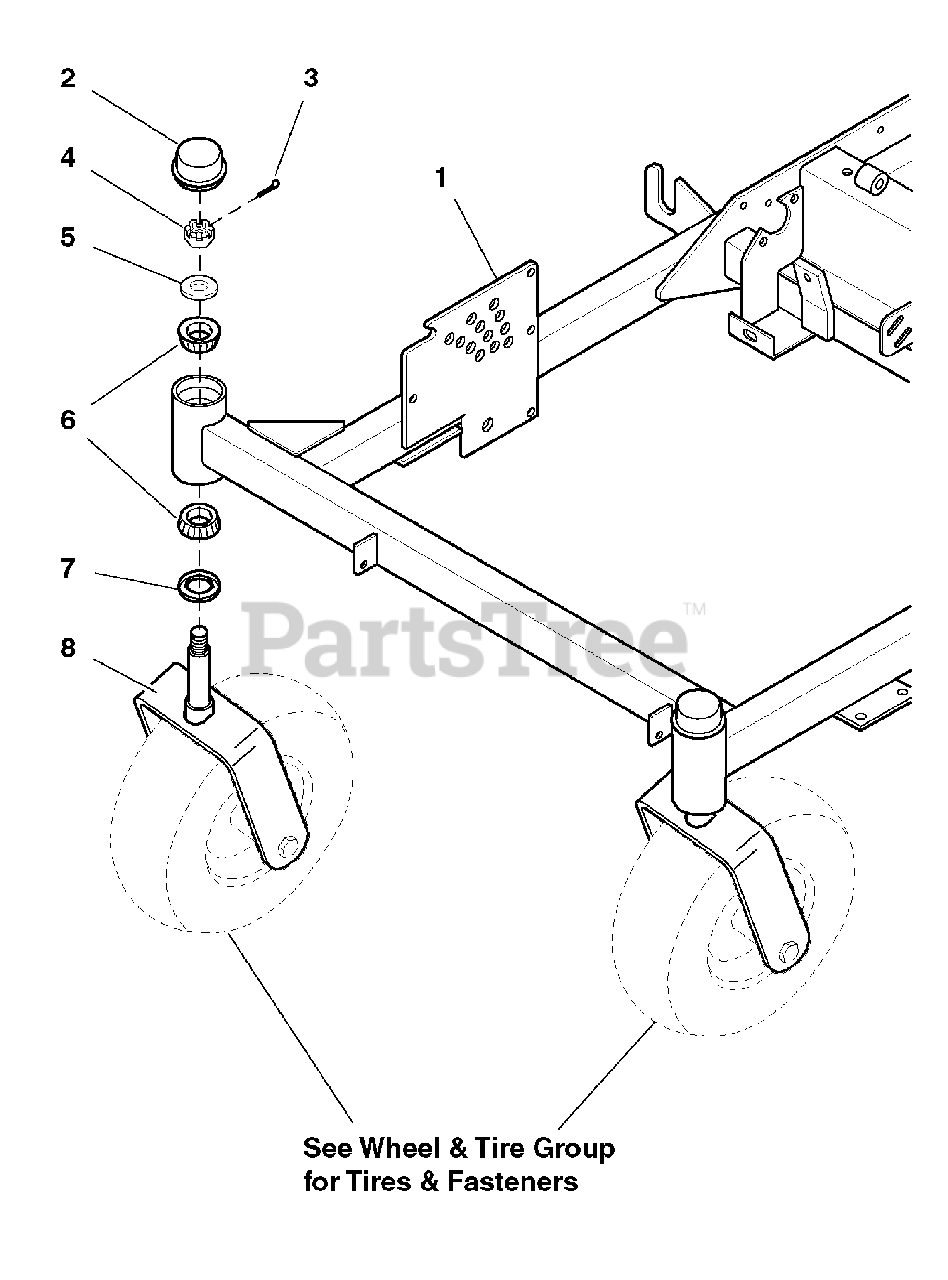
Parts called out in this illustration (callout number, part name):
1	MAIN FRAME
4	NUT, Hex, Slotted, 3/4-16
5	WASHER, 3/4
6	BEARING, Tapered Roller
7	SEAL, Grease
8	CASTER YOKE
